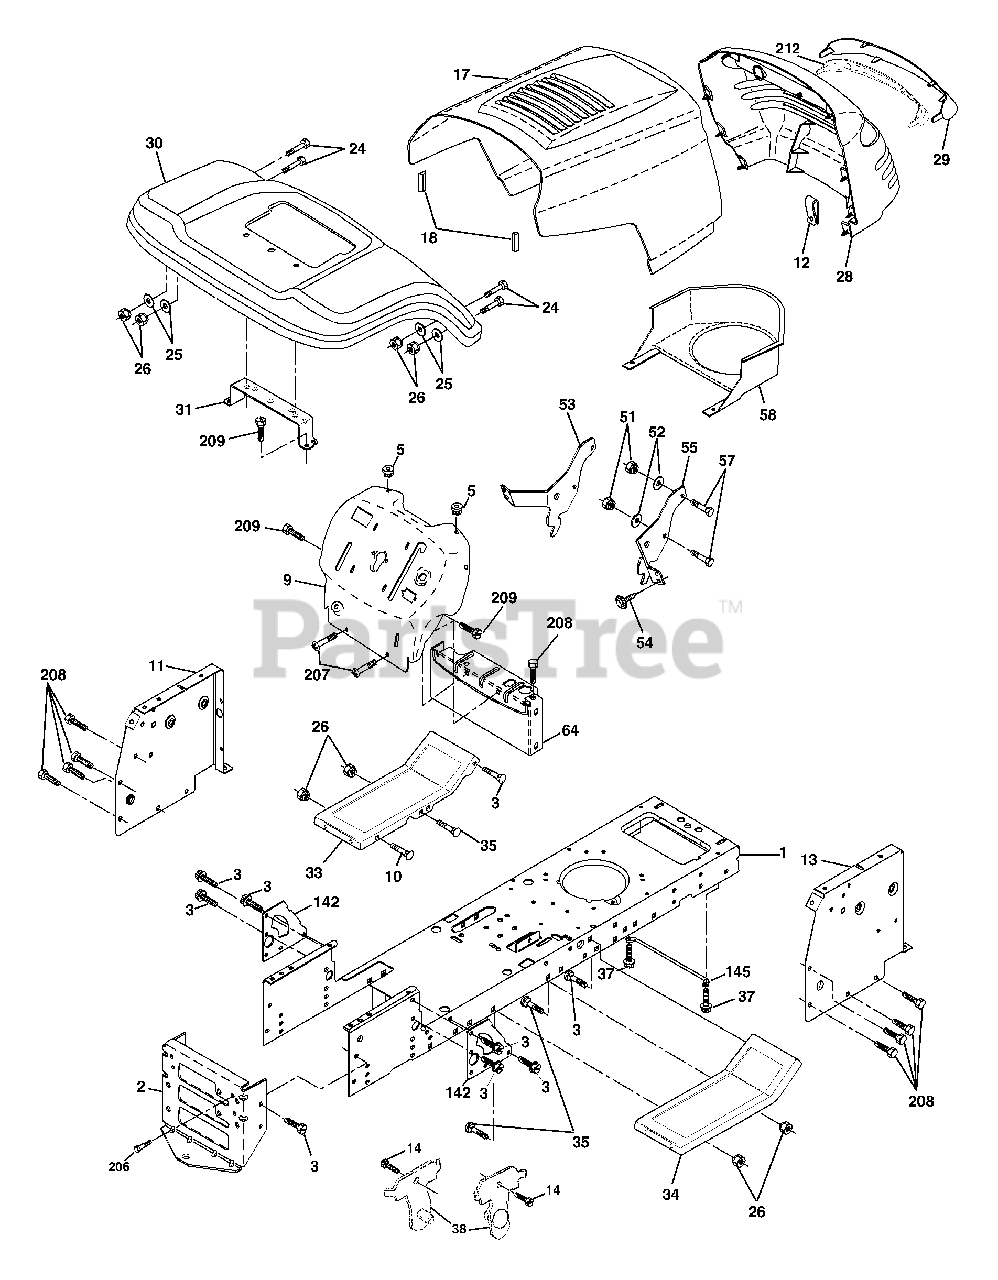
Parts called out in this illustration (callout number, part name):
1	Chassis
2	Drawbar
3	Screw 3/8-16x.75
5	Bumper Hood/Dash
9	Dash
10	Bolt Carriage 3/8-16 x 1
11	Panel Dash Lh
12	Clip Tinnerman
13	Panel Dash Rh
14	Screw Thdrol 3/8-16 x 1-1/4
17	Hood
18	Bumper Hood Large
20	Plate Battery
23	Bushing Snap
24	Bolt Fin Hex 3/8-16 x 1 Gr 5
25	Washer 13/32 X 13/16 X 12 Ga
26	Nut Lock Hex W/Ins 3/8-16 Unc
28	Grille LT/PL
29	Lens
30	Fender
31	Bracket Support Fender
33	Footrest Pnt Lh
34	Footrest Pnt Rh
35	Bolt Rdhd Sht Sqnk 3/8-16 x 3/4
37	Screw Thdrol 6/16-18 x 1/2 TYT
38	Bracket Asm. Pivot Mower Rear
51	Nut Lock Hex W/Ins 1/4-20
52	Washer 9/32 x 7/8 x 16 Ga.
53	Bracket Grille Lh
54	Screw Hex Wshd 8-18 x 7/8
55	Bracket Grille Rh
57	Bolt Hex 1/4-20 x 3/4
58	Duct Air Engine
64	Dash Lower STLT
142	Plate Reinforcement STLT
145	Rod Pivot Chassis/Hood
206	Bolt Shoulder 5/16-18
207	Screw Thdrol 5/16-18 x 1/2
208	Screw Thdrol 3/8-16 x 1/2
209	Screw Hexwsh Thdr 3/8-16 x 3/4
212	Insert Lens Reflect
219	Screw 5/16-18 x 3/4
